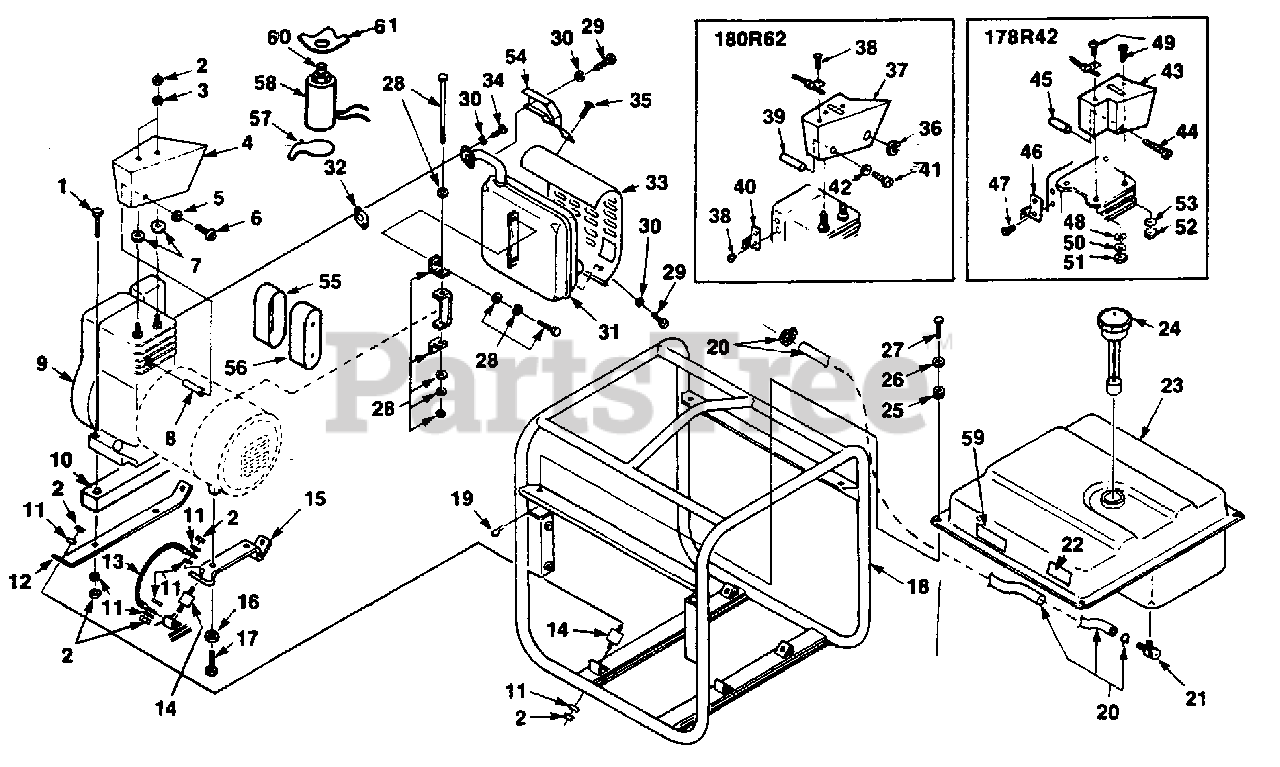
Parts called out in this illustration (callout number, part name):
1	SCREW Hex hd. 5/16-18 x 2 1/2
2	NUT-Hex 5/16-18
3	WASHER-Lock
5	WASHER-Flat #10
6	SCREW Mach Rd. Hd. 10-24 x 1 1/2
7	WASHER-Flat
11	WASHER-Int. Lock 5/16
12	SUPPORT-Engine
13	GROUND STRAP
14	VIBRATION ISOLATOR
15	SUPPORT-Generator
16	WASHER-Lock Int.
17	SCREW- Thread forming 5/16-18 x 1
18	ROLL CAGE
19	PIN-Cotter
20	FUEL LINE ASSEMBLY
21	FUEL VALVE
22	DECAL-I.D.
23	FUEL TANK
24	FUEL CAP
25	GROMMET-Isolator
26	WASHER-Flat
27	PIN-Clevis
36	GROMMET
43	DEFLECTOR-Air
44	SCREW-Hex hd 6mm x 55mm
46	BRACKET-Lite
47	SCREW #8-18 x 3/8
48	WASHER-Flat- 1/4
49	SCREW-Cap hex 1/4-20 x 1"
50	WASHER-Lock 1/4"
51	NUT-Hex 1/4-20
52	NUT-Hex 5/16-18
53	WASHER- Lock
57	ARM- Throttle
58	ELECTROMAGNET
59	DECAL- Caution
60	NUT- Hex 1/4-28
61	BRACKET- Magnet
